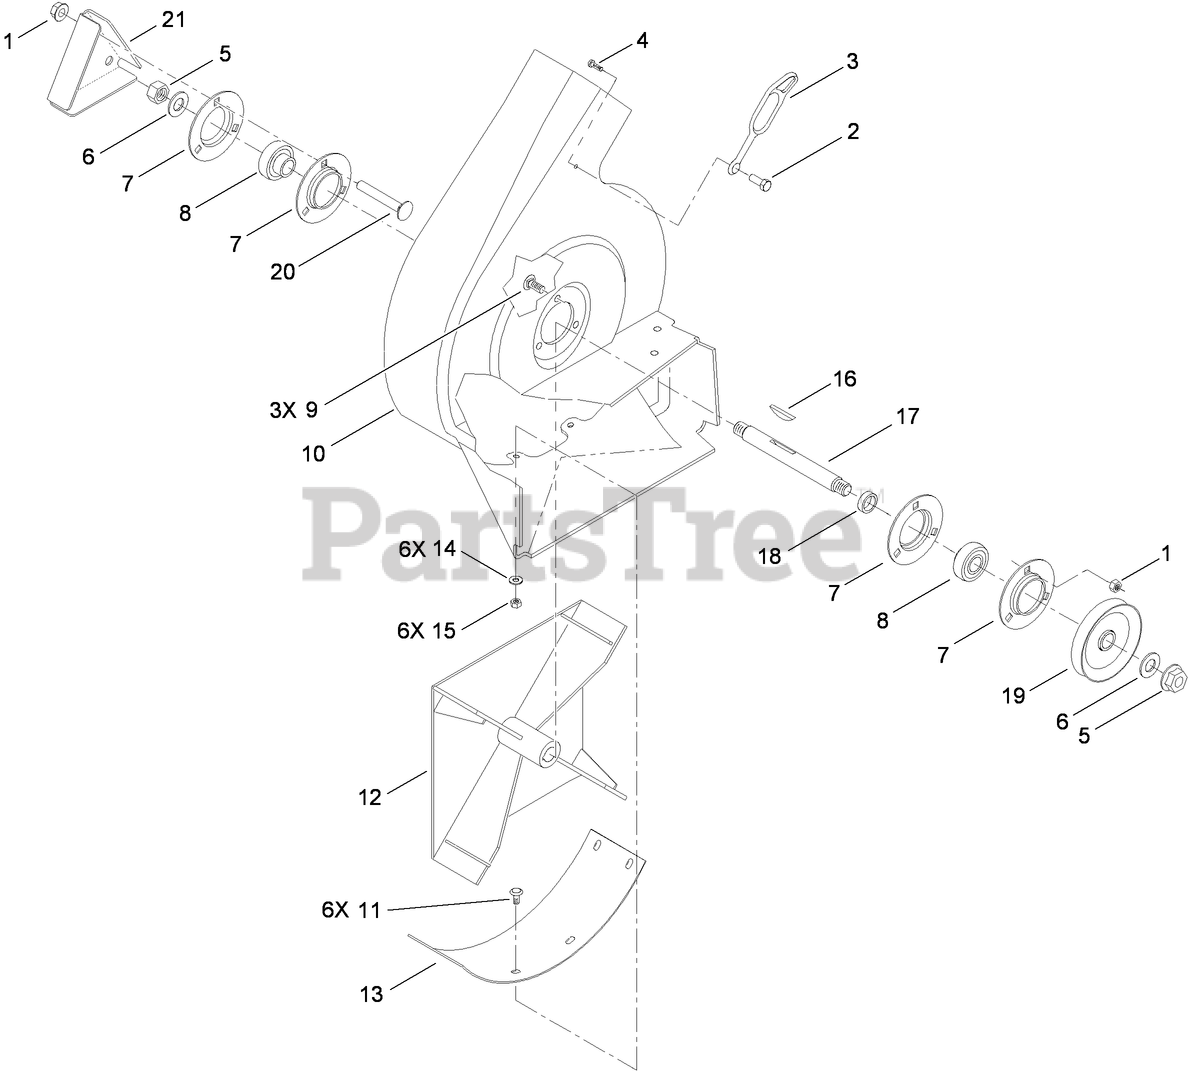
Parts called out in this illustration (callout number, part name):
1	NUT-HF
2	FASTENER-PANEL
3	RETAINER-DUCT
4	SPACER-INTERLOCK
5	NUT-JAM
6	WASHER-LOCK
7	FLANGE
8	BEARING-BALL
9	SCREW-CARR
12	IMPELLER ASM
13	COVER-BLOWER, BOTTOM
14	WASHER-FLAT
15	NUT-LOCK, NI
17	SHAFT-BLOWER
18	SPACER
19	PULLEY-BLOWER
20	BOLT-CARR
